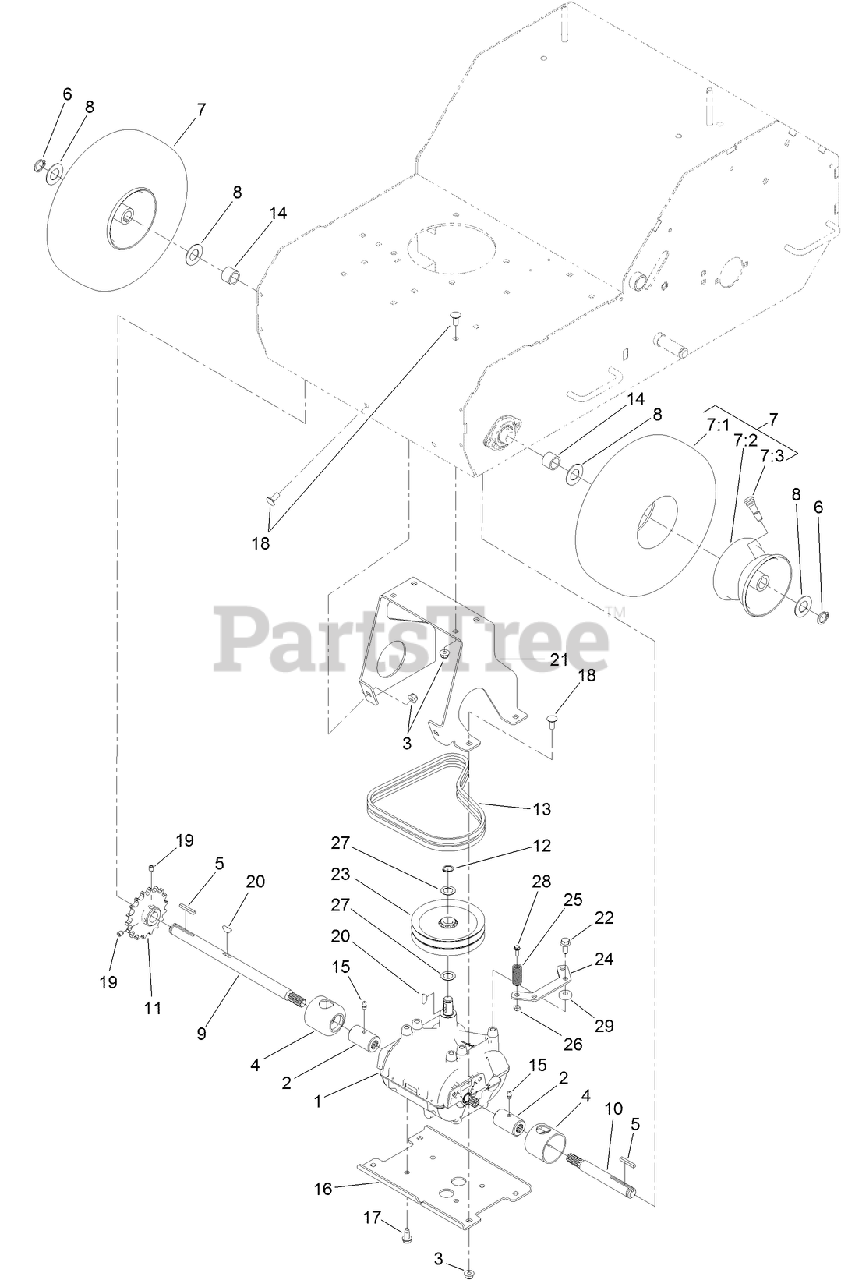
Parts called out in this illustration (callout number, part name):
1	TRANSMISSION
2	COUPLER
3	NUT-HF, NI
4	GUARD-COUPLER
5	KEY-SQUARE
6	RING-RETAINING
7	WHEEL ASM
7:2	WHEEL-RIM
7:3	VALVE
8	WASHER-FLAT
9	SHAFT-TRANSMISSION
10	SHAFT-TRANSMISSION
11	SPROCKET
12	RING-SNAP, EXTERNAL
13	BELT-V, MATCHED PAIR
14	SPACER-LOCKUP
15	FITTING-GREASE
16	MOUNT-TRANSMISSION, LOWER
17	SCREW-HWH, THREAD CUT
18	SCREW-CARR
19	SCREW-HSH
20	KEY-WOODRUFF
21	CHANNEL-MOUNT, TRANSMISSION
22	SCREW-HHF
23	SHEAVE
24	GUIDE-SPRING, MOUNT
25	SPRING-RETAINER
26	NUT-LOCK, NI
27	WASHER-FLAT
29	WASHER
